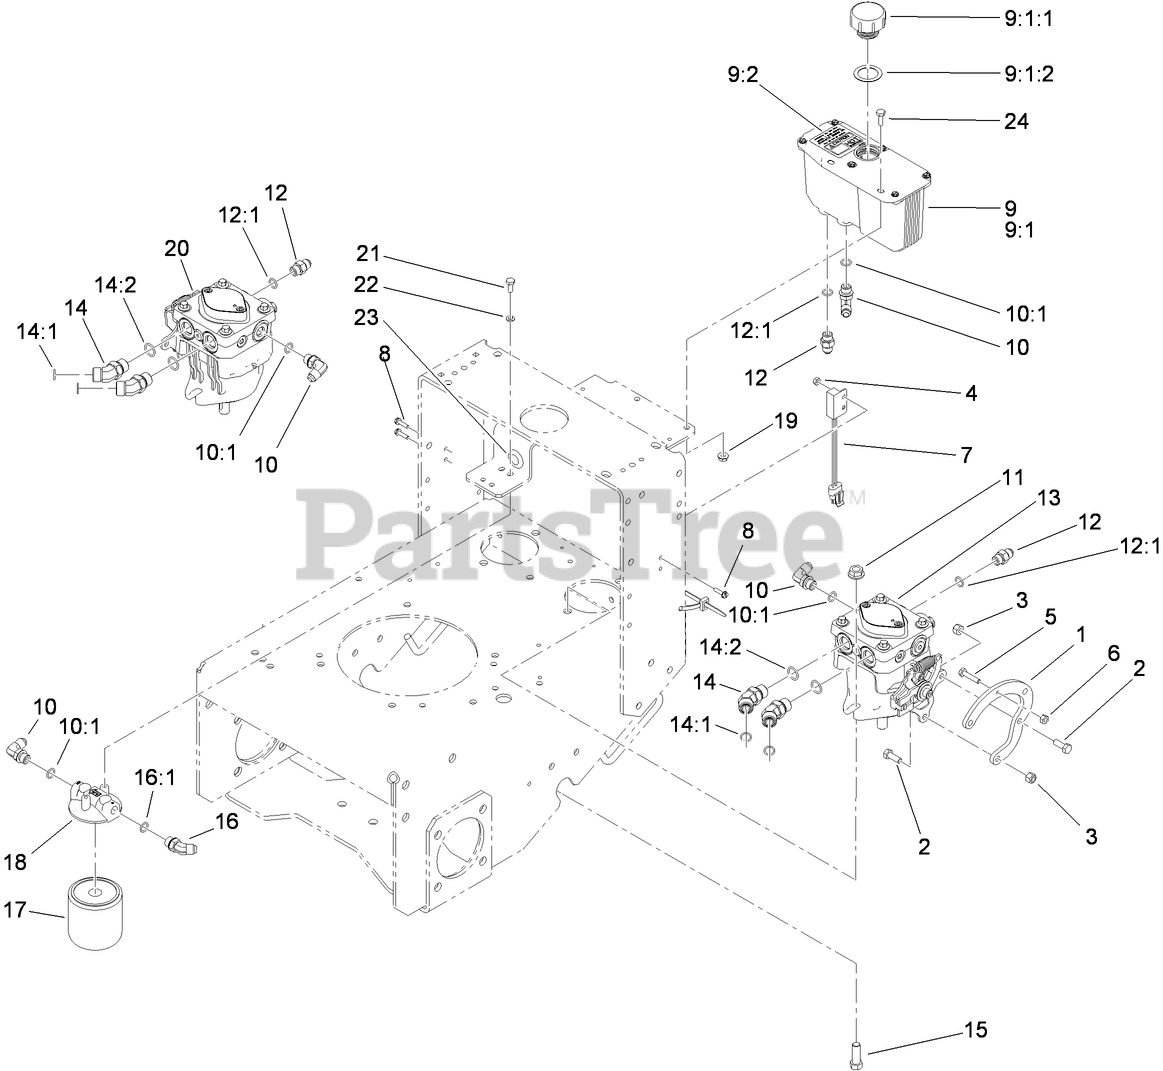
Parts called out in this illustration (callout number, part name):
1	BRACKET-ADAPTER, PUMP
2	SCREW-HH
3	NUT-LOCK, NI
4	NUT-LOCK, NI
5	SCREW-HH
6	NUT-HEX
7	SWITCH-PROXIMITY
8	SCREW-HWH
9	HYD RESERVOIR ASM
9:1	Reservoir-HYD
9:1:1	CAP-RESERVOIR, HYD
9:1:2	GASKET-CAP
9:2	DECAL-WARNING
10	FITTING-ELBOW, 90 DEG
10:1	O-RING
11	NUT-HF
12	FITTING-STRAIGHT
12:1	O-RING
13	HYD PUMP ASM
14	FITTING-HYD, 45 DEG
14:1	O-RING
14:2	O-RING
15	SCREW-HH
16	FITTING-ELBOW, 45 DEG
16:1	O-RING
17	FILTER-OIL, HYD
17	FILTER-OIL, HYD (WINTER)
18	HEAD-FILTER
19	NUT-HF
20	HYD PUMP ASM
21	SCREW-HH
22	WASHER-LOCK
23	GROMMET
24	SCREW-HH
